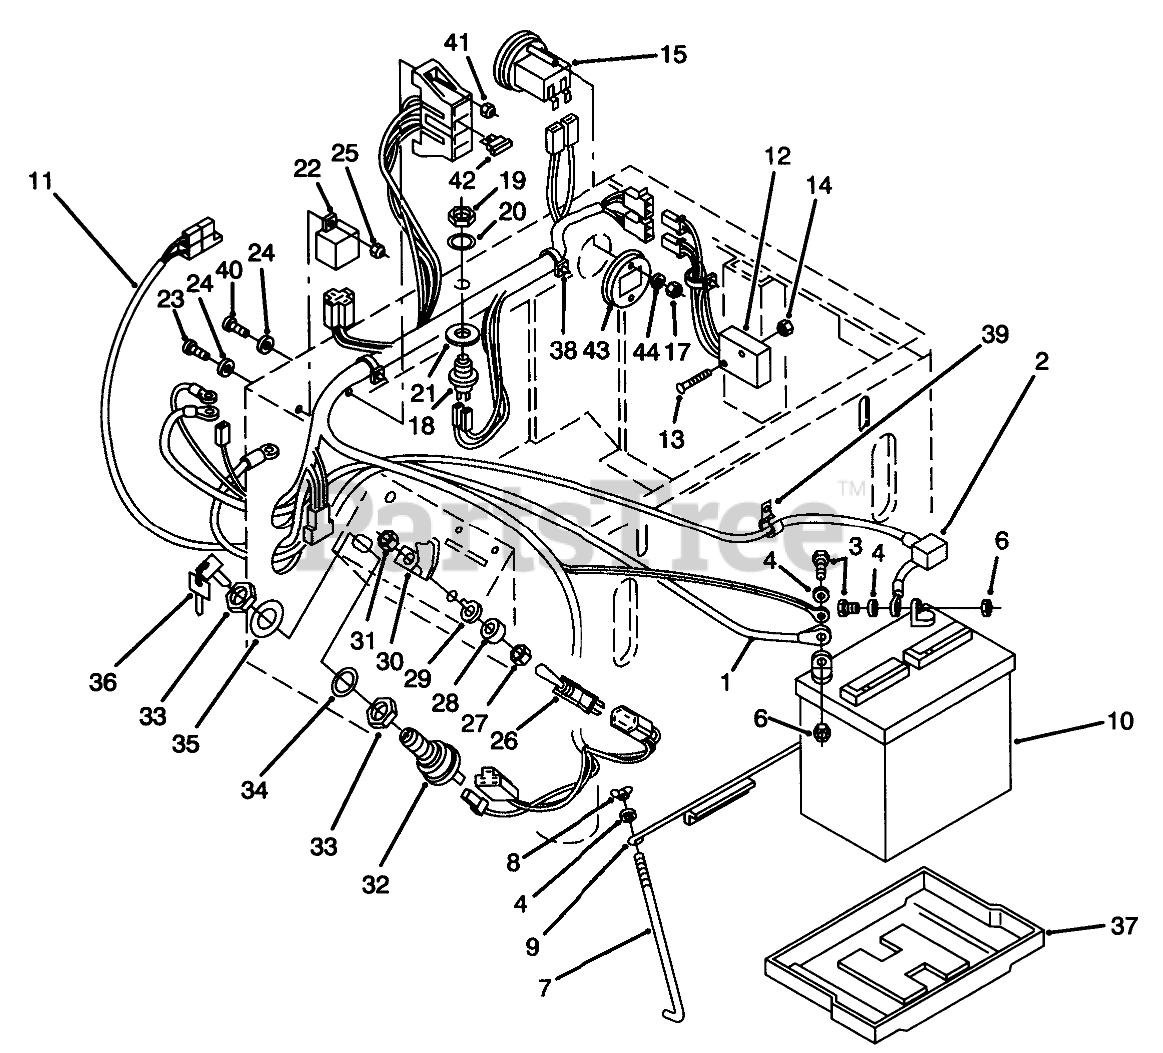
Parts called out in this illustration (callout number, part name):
1	WIRE ASM
2	Boot
3	SCREW-HH
4	WASHER-FLAT
6	NUT-LOCK, NI
7	HOOK-BATTERY RETAIN
8	NUT-WING
9	HOLDDOWN-BATTERY
10	Battery
11	WIRE HARNESS ASSY
12	SWITCH-ASS'Y NEUTRAL
13	SCREW-PPH
14	Nut
15	Hourmeter
17	Nut
18	SWITCH-PLUNGER
19	HEX-NUT 5/8-24 F/W 116194
20	LOCKWASHER
21	WASHER-FLAT
22	RELAY
24	WASHER-FLAT
25	Nut
26	SWITCH-TOGGLE DPDT
27	NUT-HEX, SPECIAL
28	WASHER
29	TAB-WASHER
30	COVER-PTO SWITCH
32	SWITCH, KEY ASS'Y
33	HEX-NUT 13/16 UNEF
34	Washer-Lock
35	WASHER-SPECIAL
36	KEY-PADDED TORO CUT
37	TRAY-BATTERY
38	CLIP-SNAP IN
39	J-CLIP
41	Nut
42	FUSE-10 AMP
43	CLAMP-HOUR METER
44	WASHER-LOCK
